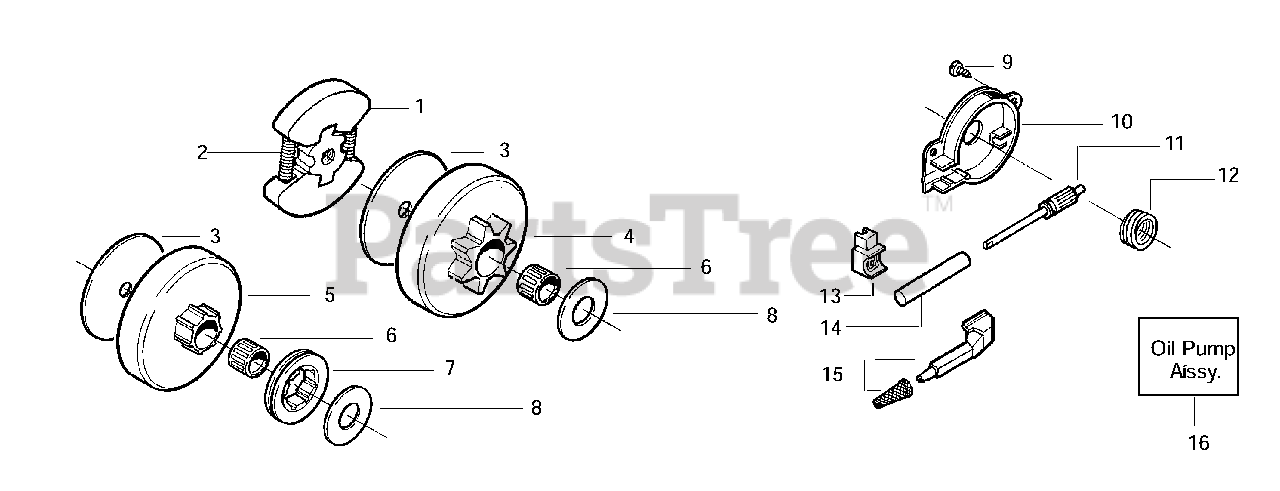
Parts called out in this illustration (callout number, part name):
1	Clutch Assembly
2	Spring - Clutch
3	Clutch Washer
4	Clutch Drum w/Bearing Assy. (3/8x6 spur)
5	Drum, Adapt. & Bearing Kit
6	Clutch Bearing
7	Rim-Floating (.325)
8	Thrust Washer
10	Oil Pump Housing
11	Plunger & Gear Assembly
12	Oil Pump Worm
13	Oil Seal
14	Oil Pump Barrel
15	Oil Pick-Up and Screen Assembly
16	Oil Pump Assembly
